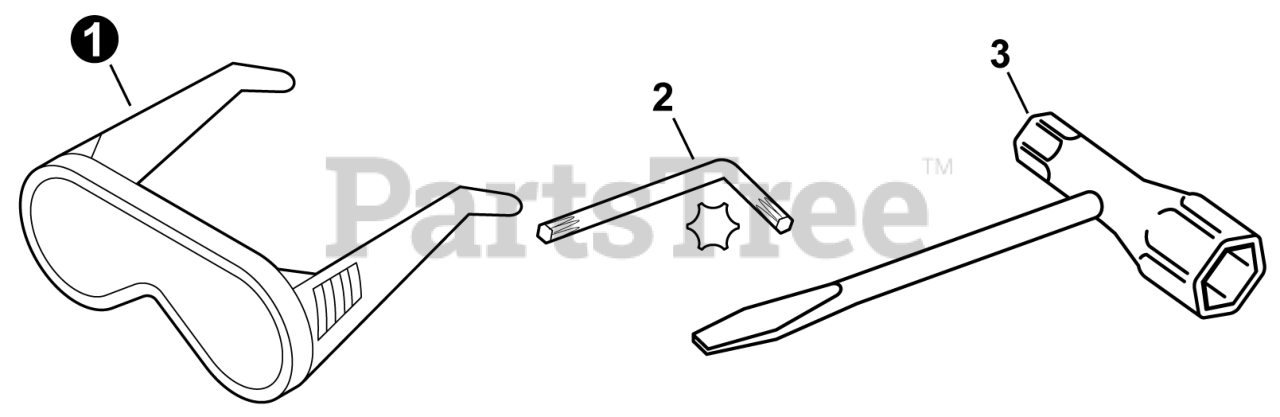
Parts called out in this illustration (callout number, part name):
1	GLASSES, SAFETY
2	WRENCH, T27 80×30
3	T-WRENCH 10×19 MM
